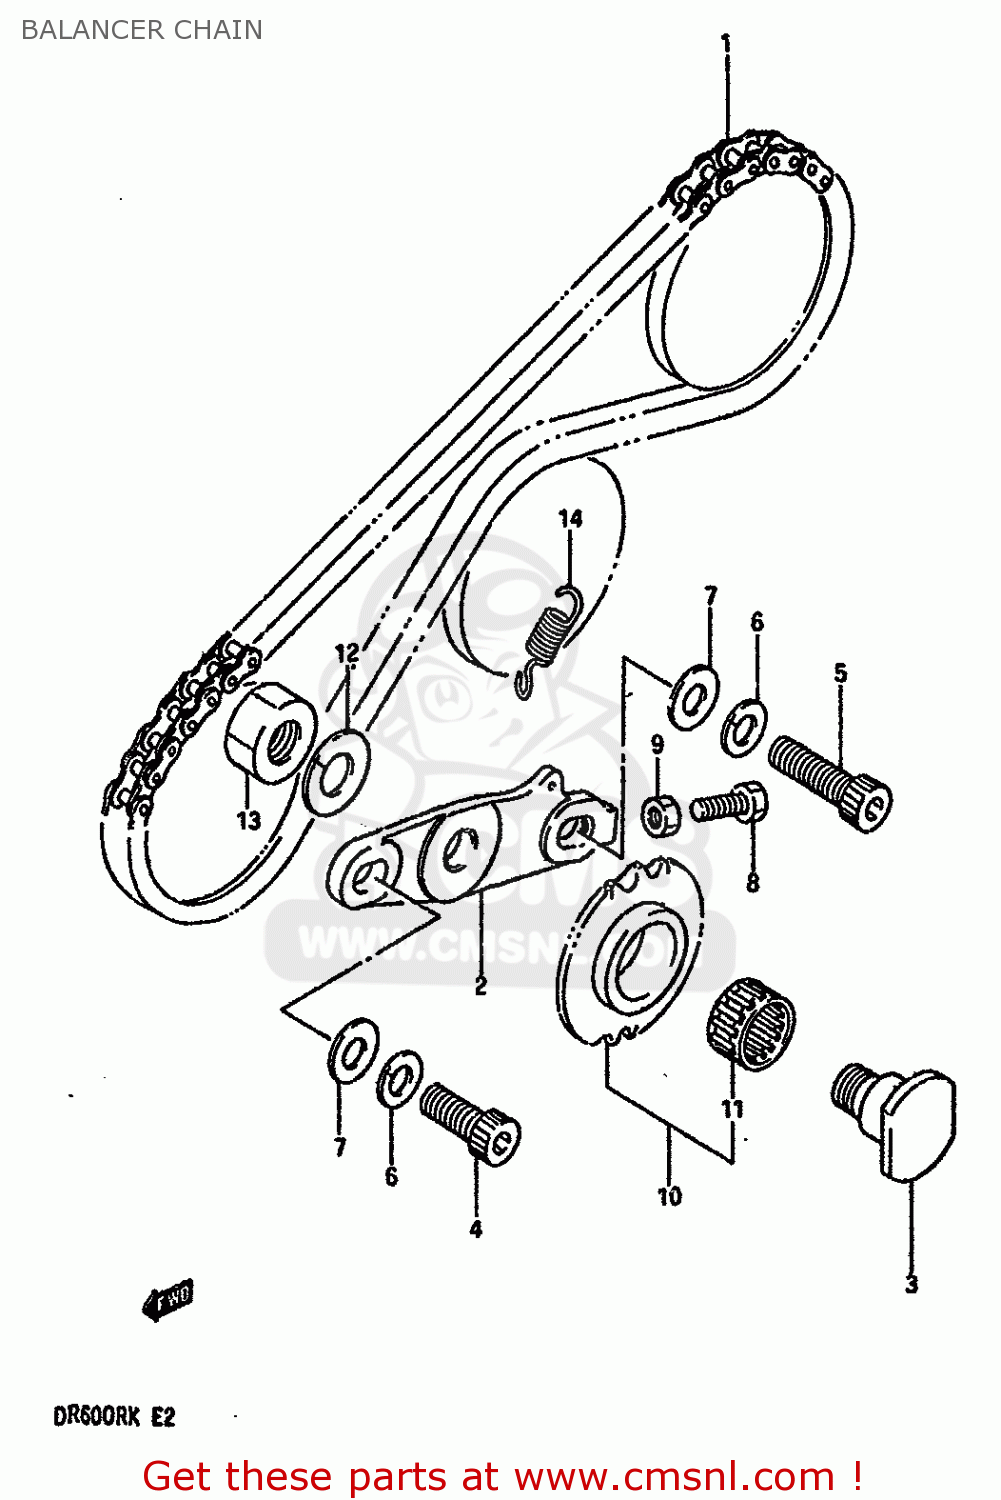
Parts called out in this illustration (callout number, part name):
1	CHAIN,BALANCER
2	BRACKET,BALANCER CHAIN
3	SHAFT,BALANCER CHAIN TENSIONER
4	BOLT(8X22)
5	BOLT, REAR (8X30)
6	LOCK WASHER
7	WASHER
8	BOLT 5X20
9	NUT
10	SPROCKET,BALANCER CHAIN
11	BEARING(17X23X12)
12	WASHER,LOCK 12
13	NUT
14	SPRING
